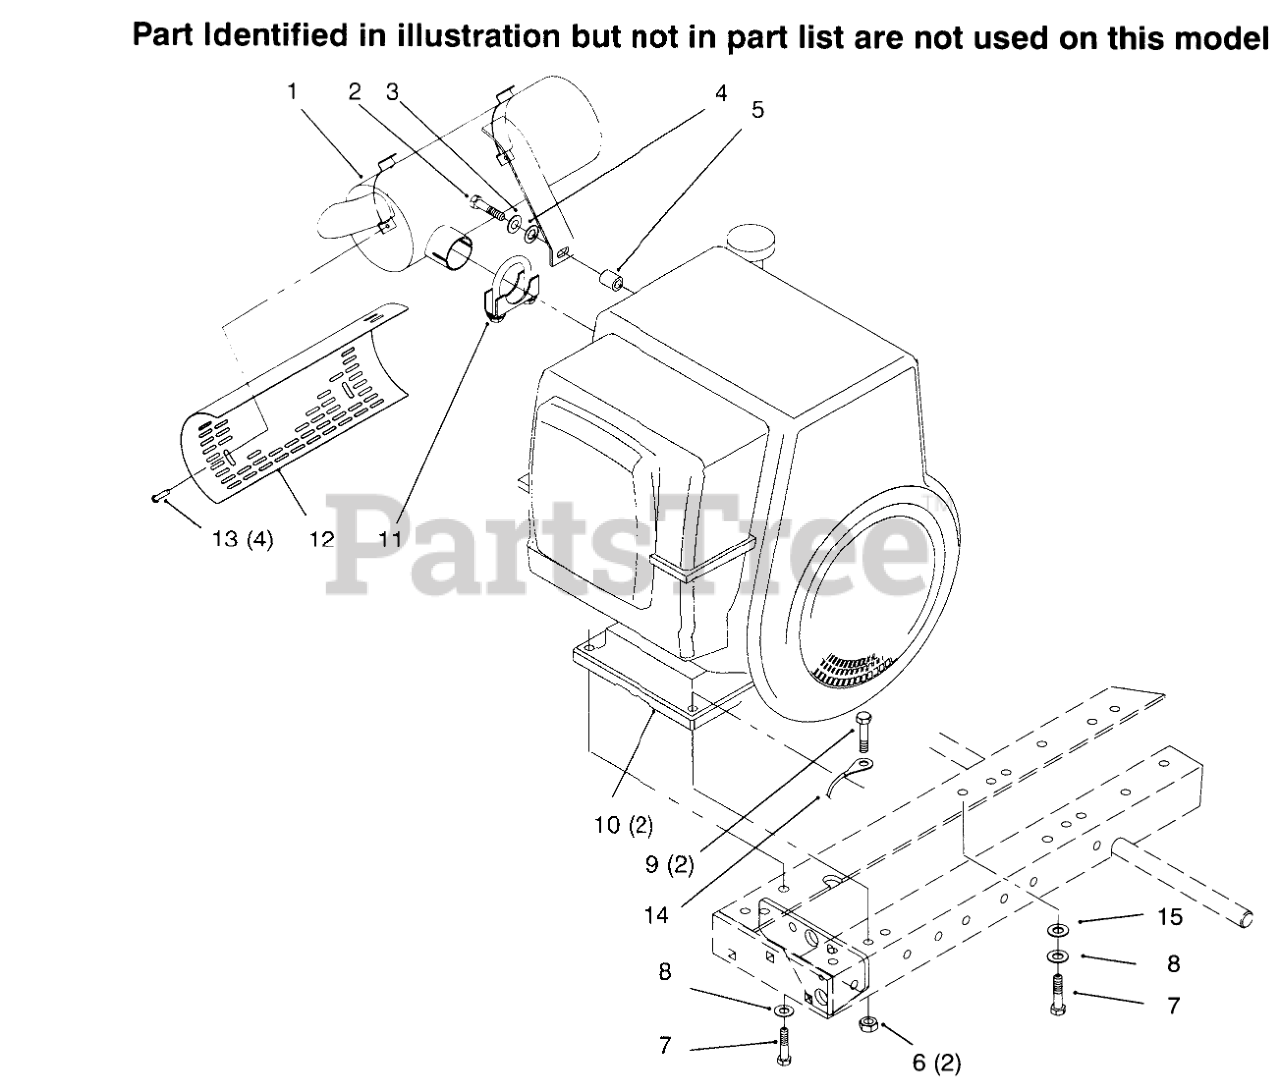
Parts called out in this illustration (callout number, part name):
1	MUFFLER
2	SCREW-HH
3	WASHER-LOCK
4	WASHER-PLAIN
5	SPACER
6	NUT-LOCK, NI
7	SCREW-HH
8	WASHER-LOCK
9	SCREW-HH
10	Engine-14HP
11	CLAMP-1 1/2
12	SHIELD-HEAT
13	SCREW
14	WIRE GROUND
15	WASHER-LOCK
